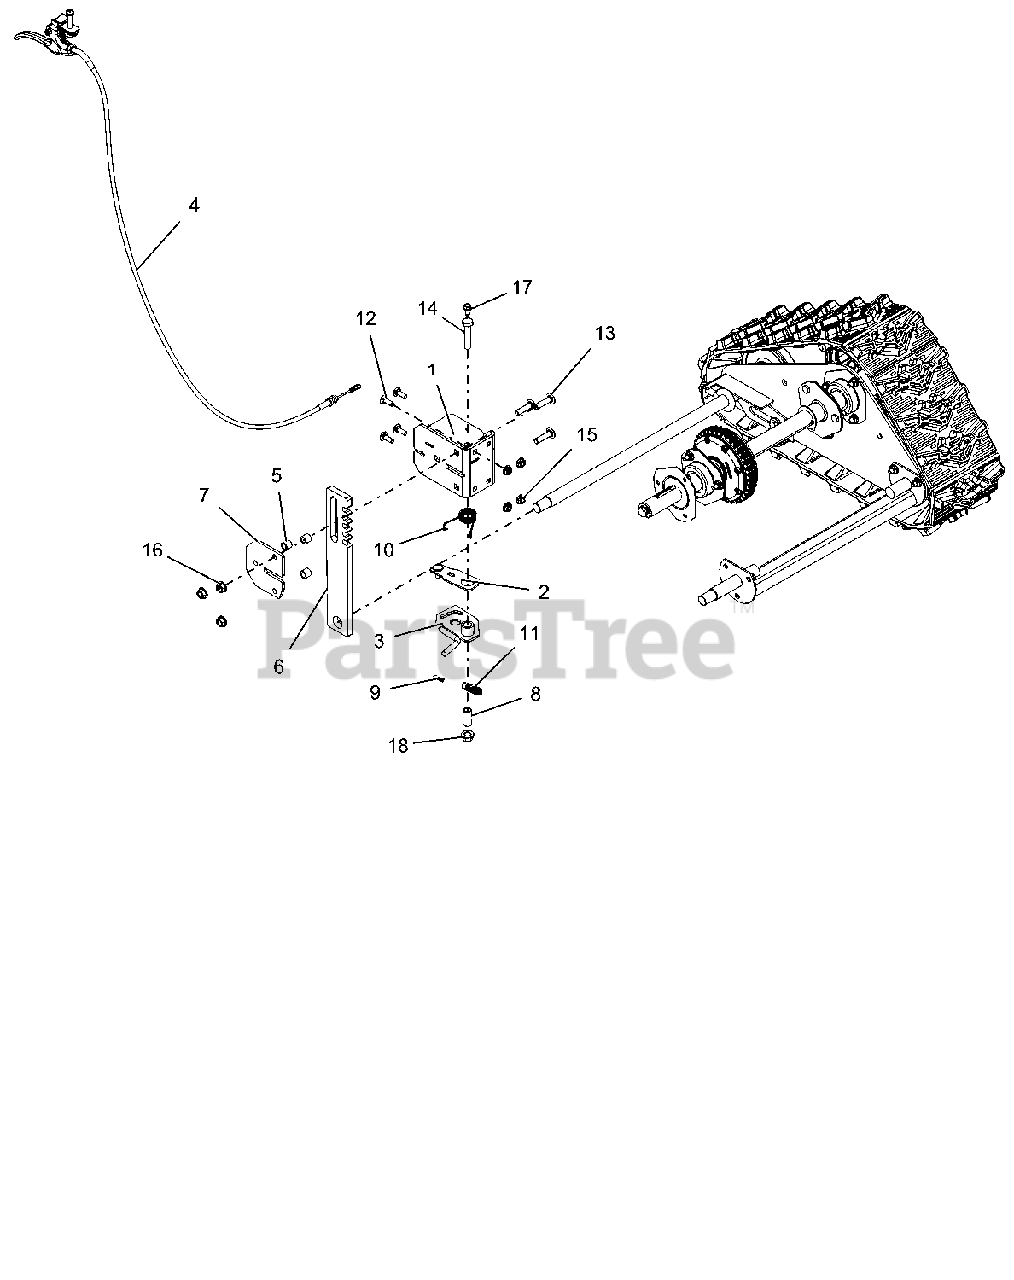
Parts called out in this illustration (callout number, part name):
1	BRACKET, HEIGHT ADJUSTER
2	ARM, OVERTRAVEL
3	LOCK, HEIGHT ADJUSTER
4	CABLE, TRACK REMOTE
5	SPACER .50 X .32 X .42
6	STOP, HEIGHT ADJUSTER - DELUXE
7	PLATE, HEIGHT ADJUSTER
8	BSHG-SLV .385X.500X1.045
9	PIN-HAIR INT .06X.18X.77
10	SG-TORS .067X.88
11	SPRING-EXT .047 X .438 X 1.85
12	@BLT-RDHDSQNK .25-20X.75 G5YZ
13	@BLT-RHDSHSQNK.31-18X1.25 G5YZ
14	@BLT-HEX .38-16X1.75 GR5 YWZC
15	@NUT-LK-CTR-FLG .25-20 YWZC
16	@NUT-LK-TOP-FLG .31-18 YWZC
17	SCR-TAP .25-20X.50 HWH TR YWZ
18	NUT-LK-CTR-FLG .38-16 YWZC
